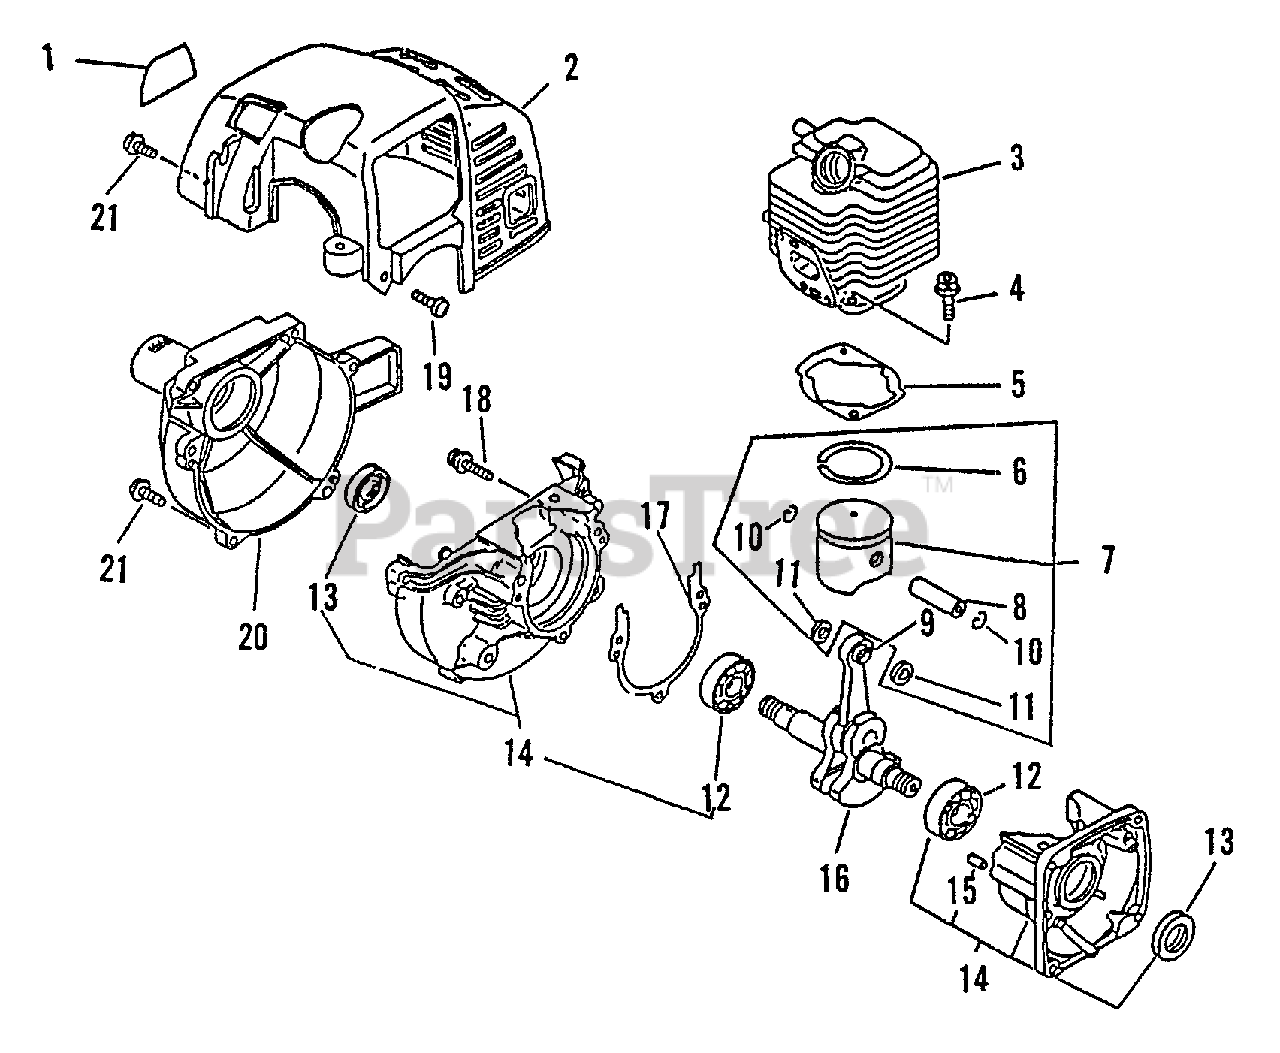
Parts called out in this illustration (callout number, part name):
1	LABEL, MODEL
2	COVER, ENGINE - GRAY
4	BOLT 5×22
5	GASKET, CYLINDER
6	RING, PISTON
7	PISTON KIT
8	PIN, PISTON 8
9	BEARING, NEEDLE
10	RING, SNAP
11	WASHER, THRUST
12	BEARING, BALL 6201
13	SEAL, OIL 12
14	CRANKCASE KIT
15	PIN, LOCATING 4×8
16	CRANKSHAFT ASSY
17	GASKET, CRANKCASE
18	SCREW 5×28
19	SCREW 4×12
20	COVER, FAN
21	SCREW 4×16
